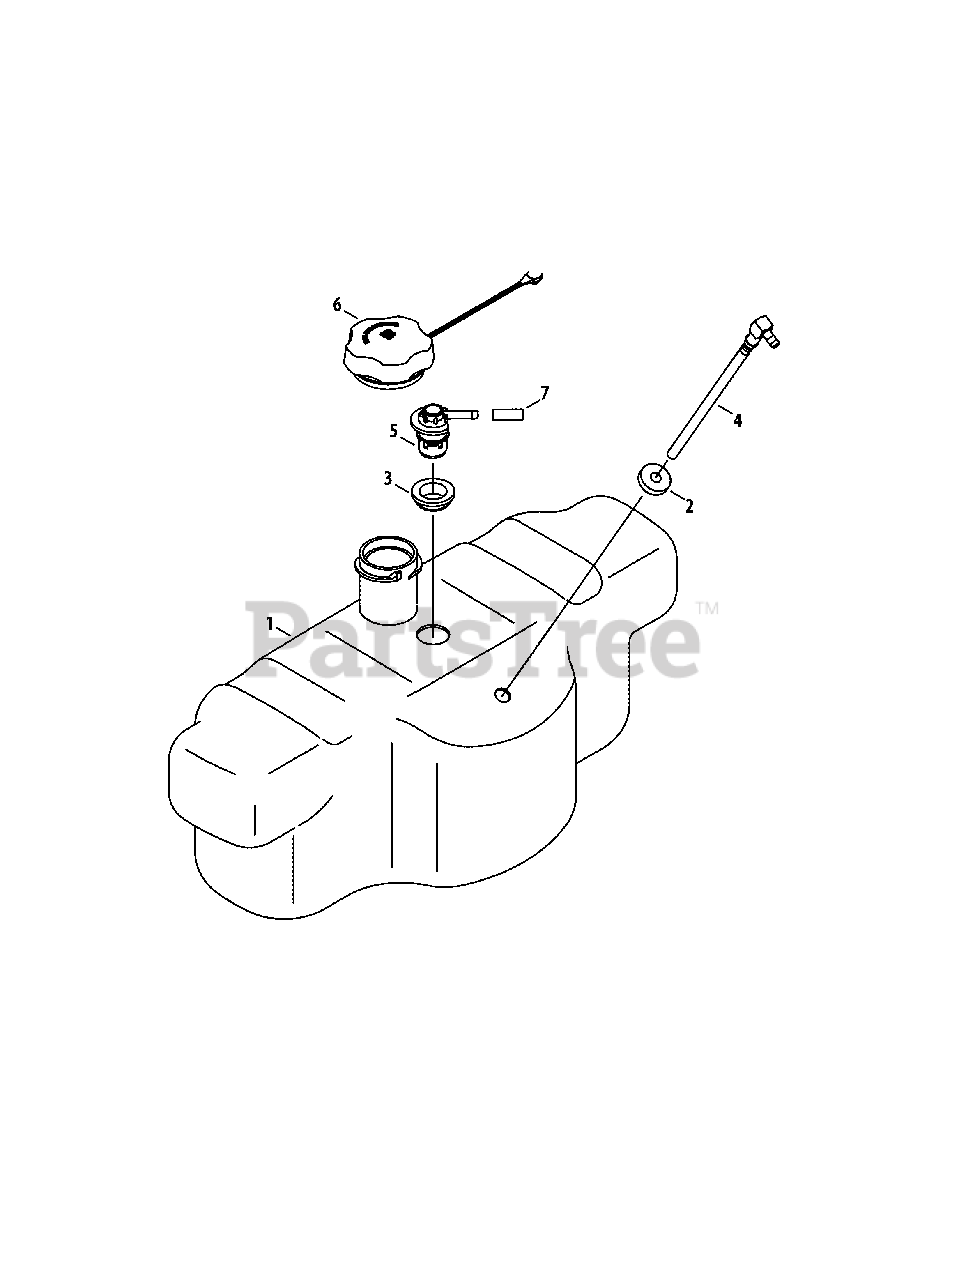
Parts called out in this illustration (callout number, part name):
1	TANK, Fuel
2	BUSHING, Fuel Tank
3	GROMMET, Rubber
4	FITTING, Fuel Pickup
5	VALVE, Rollover
6	CAP, Fuel
7	HOSE, Vent
